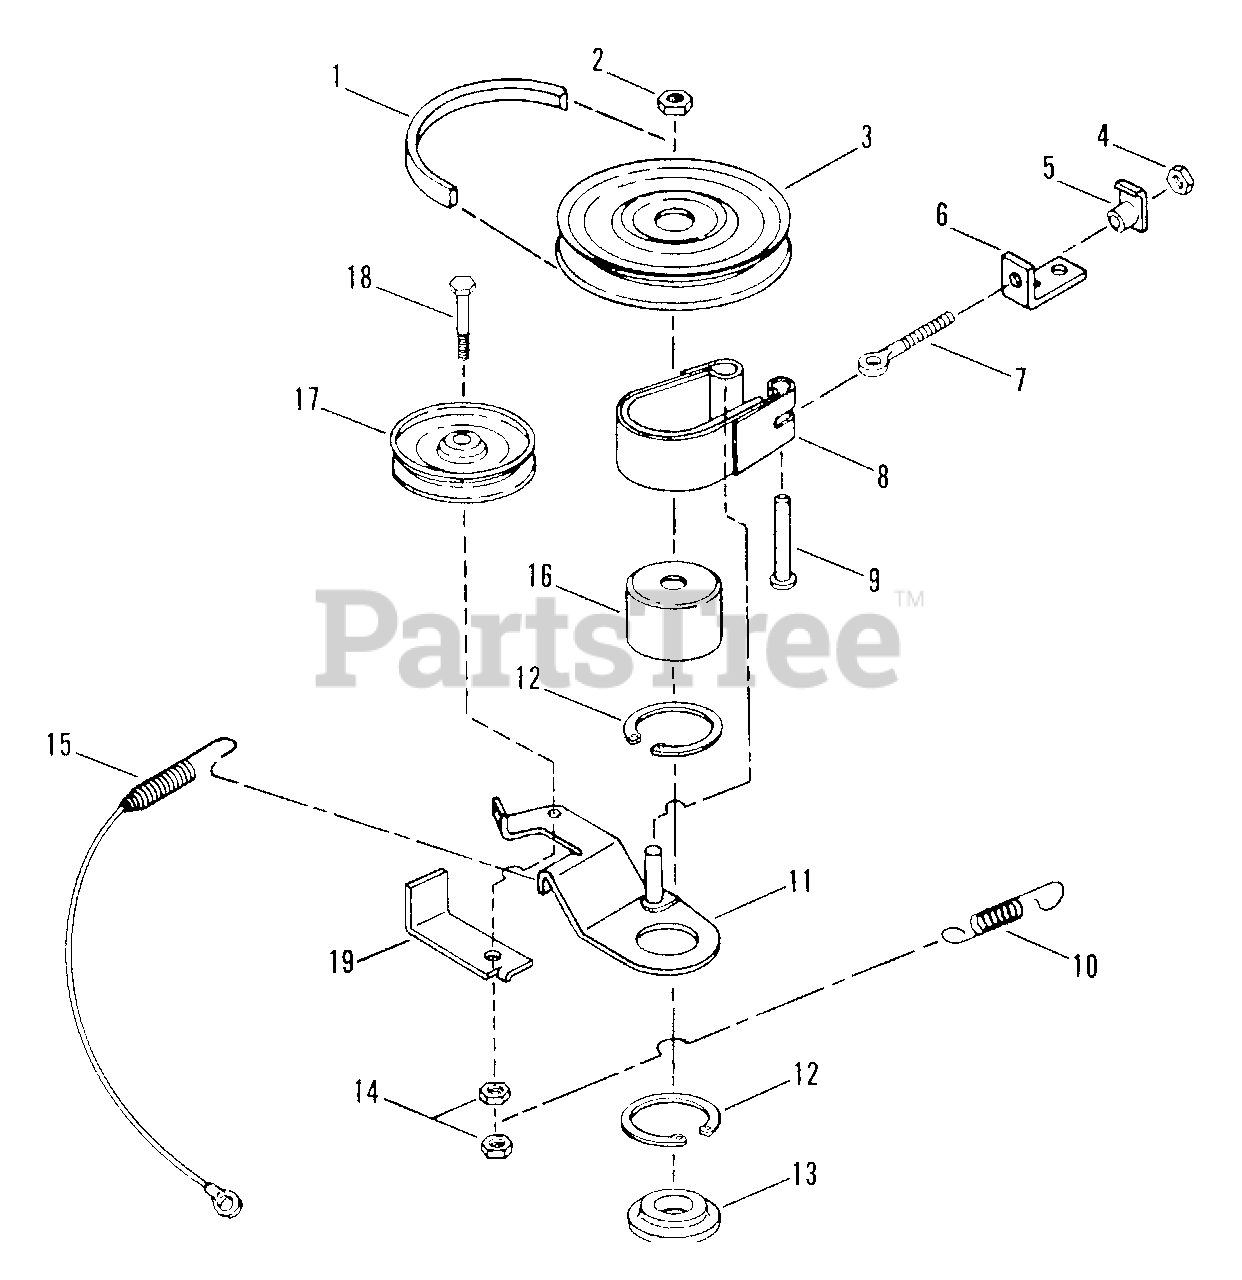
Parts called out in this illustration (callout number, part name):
1	BELT, Drive (A101)
1	BELT, Drive (HA101.7)
2	NUT, 3/4-16 Hex Jam
3	PULLEY, Drive
4	NUT, 1/4-20 Hex
5	TEE-NUT, 1/4-20
6	ANCHOR, Brake
7	BOLT, 1/4-20 Eye
8	ASSEMBLY, Brake Band
9	PIN, Clevis, 1/4 x 1 1/4"
10	SPRING, Blade Brake
11	ASSEMBLY, Brake Arm
12	RING, 2" External Retaining
13	WASHER, Spindle
14	NUT, 3/8-24 Hex Lock
15	CABLE, Blade (19.75" Long)
16	DRUM, Brake
17	PULLEY, Idler
18	SCREW, 3/8-24 x 2" Hex Head Cap
19	GUIDE, Belt
